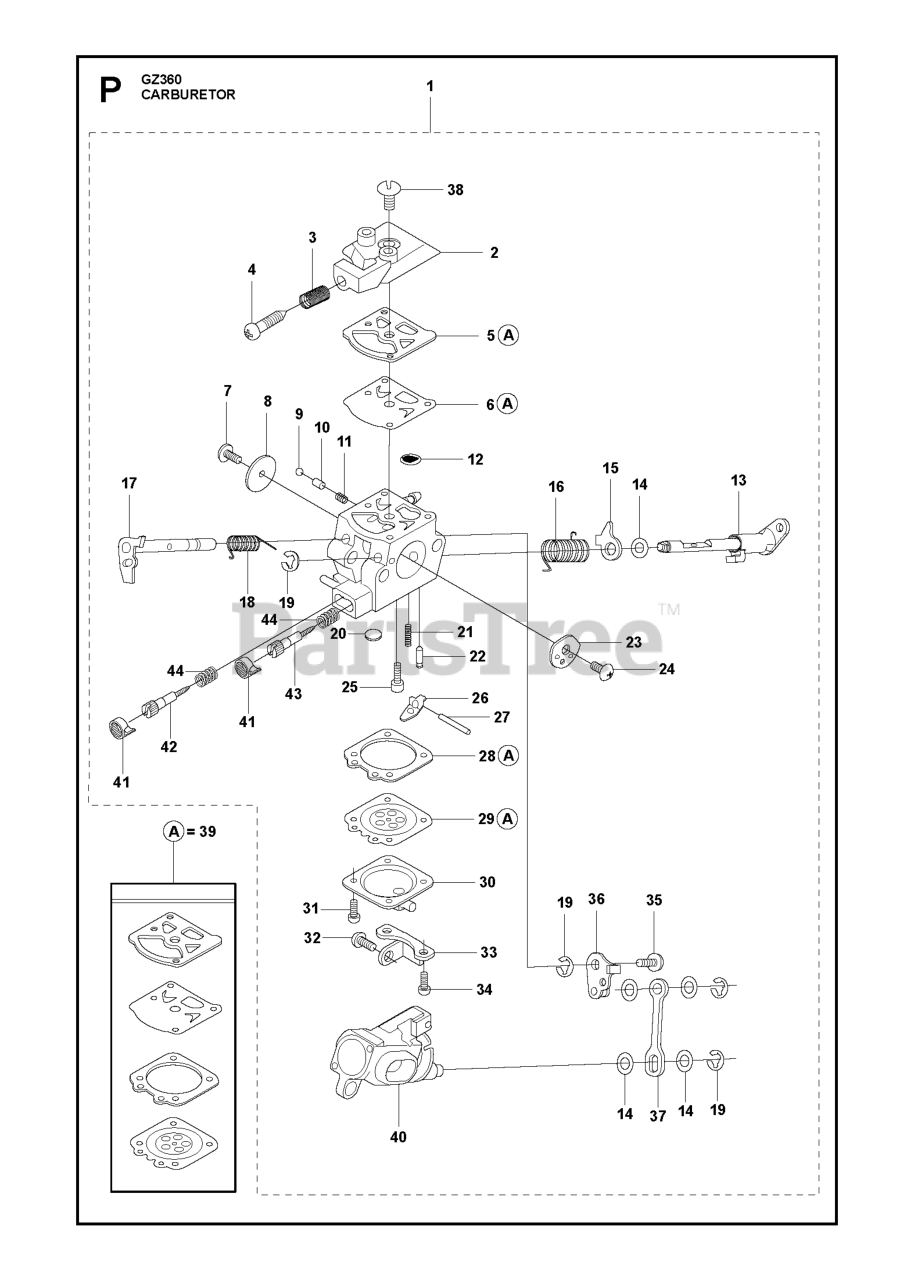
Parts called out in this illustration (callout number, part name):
1	CARBURETTOR 439
5	GASKET
6	DIAPHRAGM, FUEL PUMP
7	SCREW
9	BALL
10	PISTON
11	SPRING
12	SCREEN
13	SHAFT ASSY CHOKE 439
17	SHAFT ASST THRO
18	SPRING RETURN
21	SPRING
22	VALVE INLET
23	CHOKE VALVE
24	SCREW
28	GASKET
29	DIAPHRAGM
31	SCREW ASSY
33	BRACKET 167-596
34	SCREW ASSY
35	SCREW
36	LINK ASSY THROT 439
37	ROD, LINK
39	GASKET KIT
40	BODY ASSY AIR VALVE 5-8416
41	CAP LIMITER
43	NEEDLE H
